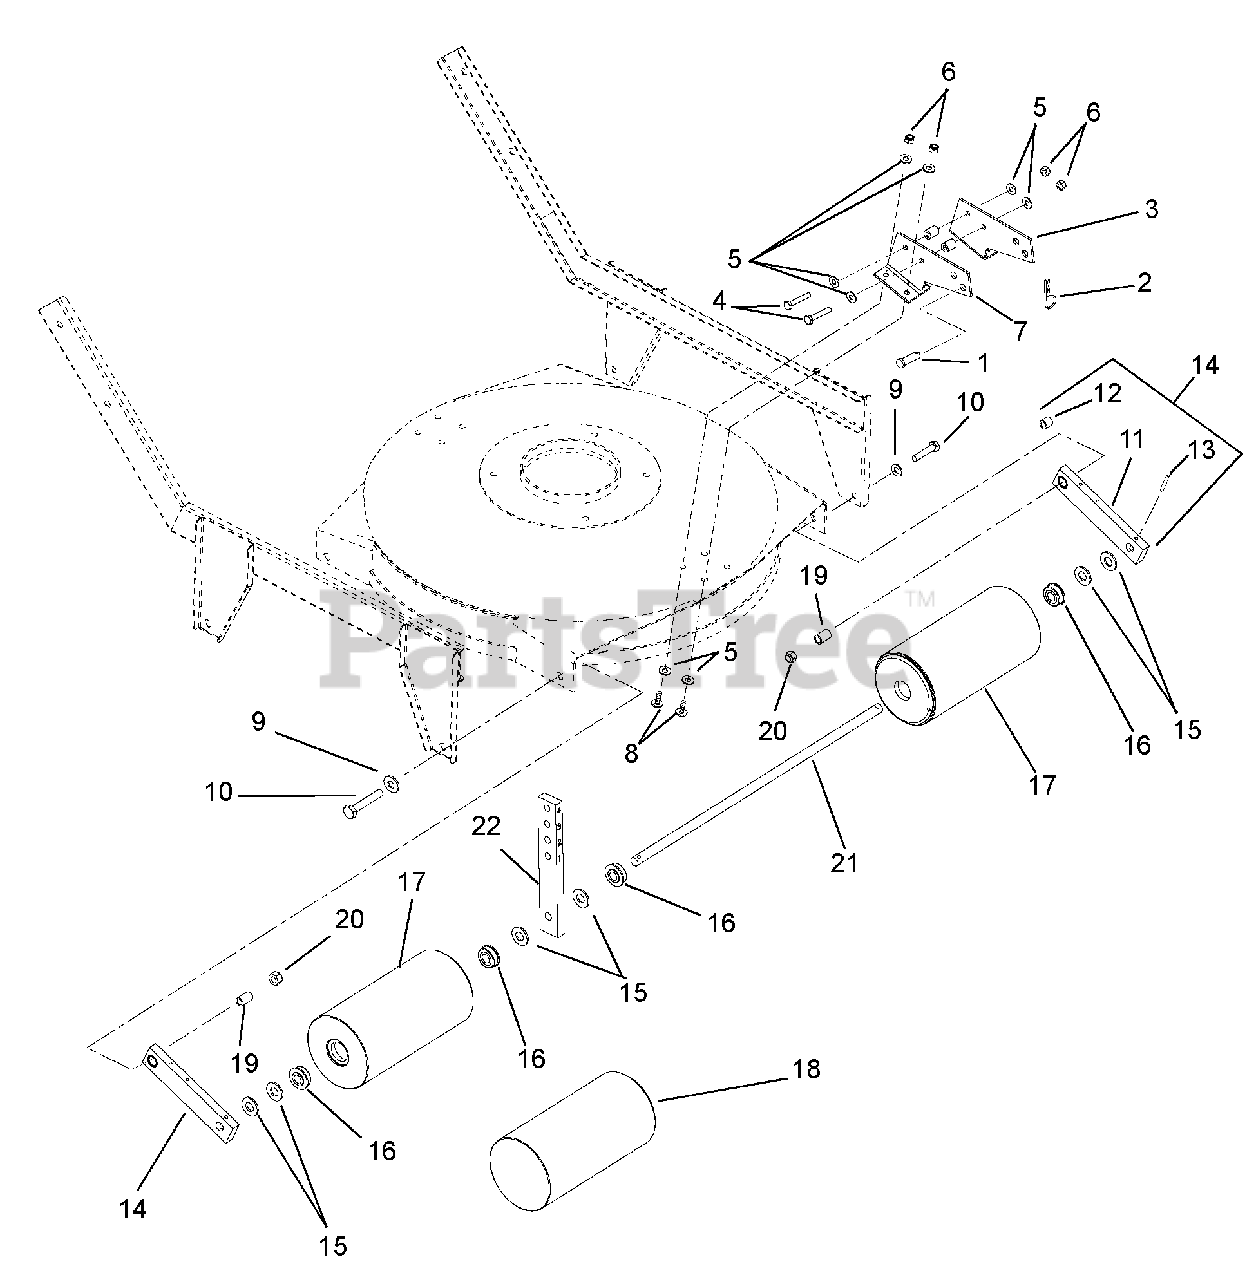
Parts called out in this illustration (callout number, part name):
1	Pin, Clevis .38 x 1.25
2	Pin, Cotter Hair
3	Bracket, Left Hand Adjustment
4	Capscrew, Hex Head .25-20 x 1.5
5	Washer, Flat .25
6	Nut, Hex Nyloc .25-20
7	Bracket, Right Hand Adjustment
8	Screw, Panhead Phillips .25-20 x .75
9	Washer, Flat .3125
10	Capscrew, Hex Head .313-18 x 1.50
11	Arm, Swing
12	Bushing, Bronze
13	Roll Pin .1875 x 1.0
14	Assembly, Swing Arm (Includes Items 11, 12 and 13)
15	Washer, Flat .50
16	Bearing, Flange
17	Roller Assembly (Includes Item 18)
18	Cover, Vinyl (Included with Item 17)
19	Shaft, Swing Arm Pivot
20	Nut, Hex Nyloc .313-18
21	Shaft, Roller
22	Bar, Adjustment
